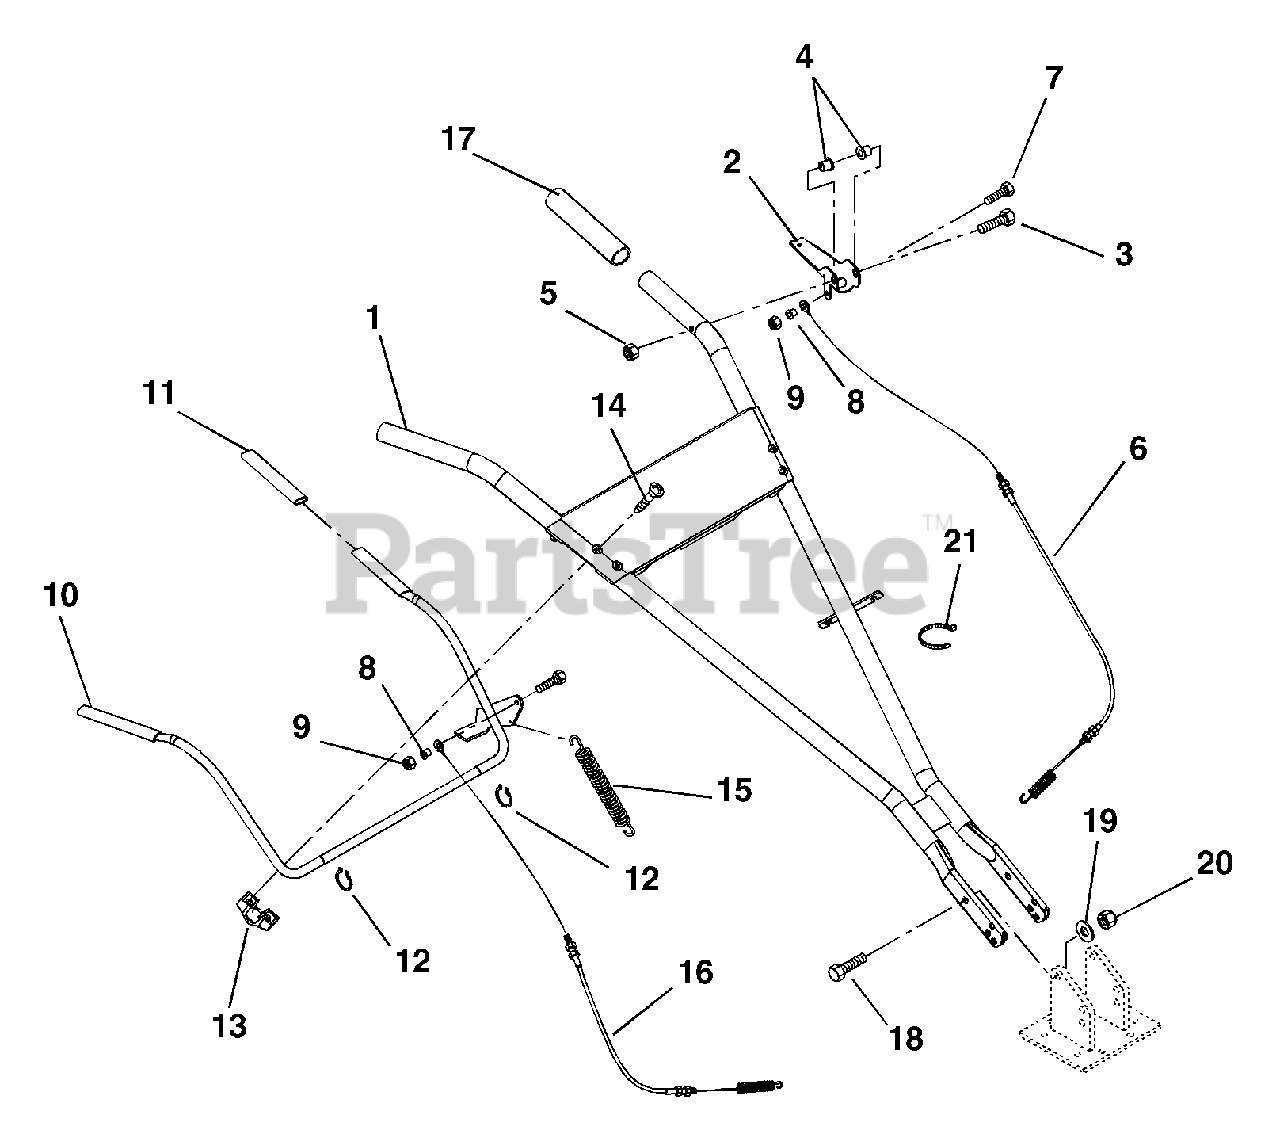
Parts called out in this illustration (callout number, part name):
1	HANDLEBAR
2	HANDLE, REVERSE
3	@BLT-HEX .31-18X2.25 GR5 YWZC
4	BSHG-FLG .325X.465X.333X.685
5	@NUT-LK-CTR .31-18 YWZC
6	CABLE, REVERSE
7	@BLT-HEX .25-20X1.00 GR5 YWZC
8	BSHG-FLG .253X.373X.385X.500
9	@NUT-LK-CTR .25-20 YWZC
10	BAIL, FWD
11	GRIP, TILLER - OPC
12	RG-RTNG-EXT .500X.042 (E)
13	PIVOT, BAIL
14	SCR-TAP 12-24X1.50 CROVH YZ BT
15	SG-TENS .051X.50X5.12 WLD 10.4
16	CABLE, FWD. SER. 18"
17	HANDLEGRIP
18	@BLT-HEX .38-16X1.00 GR5 YWZC
19	@WSHR-FL-STL.438X1.00X.083 YWZ
20	@NUT-LK-CTR .38-16 YWZC
21	TIE WRAP, BLACK LG 7.31
